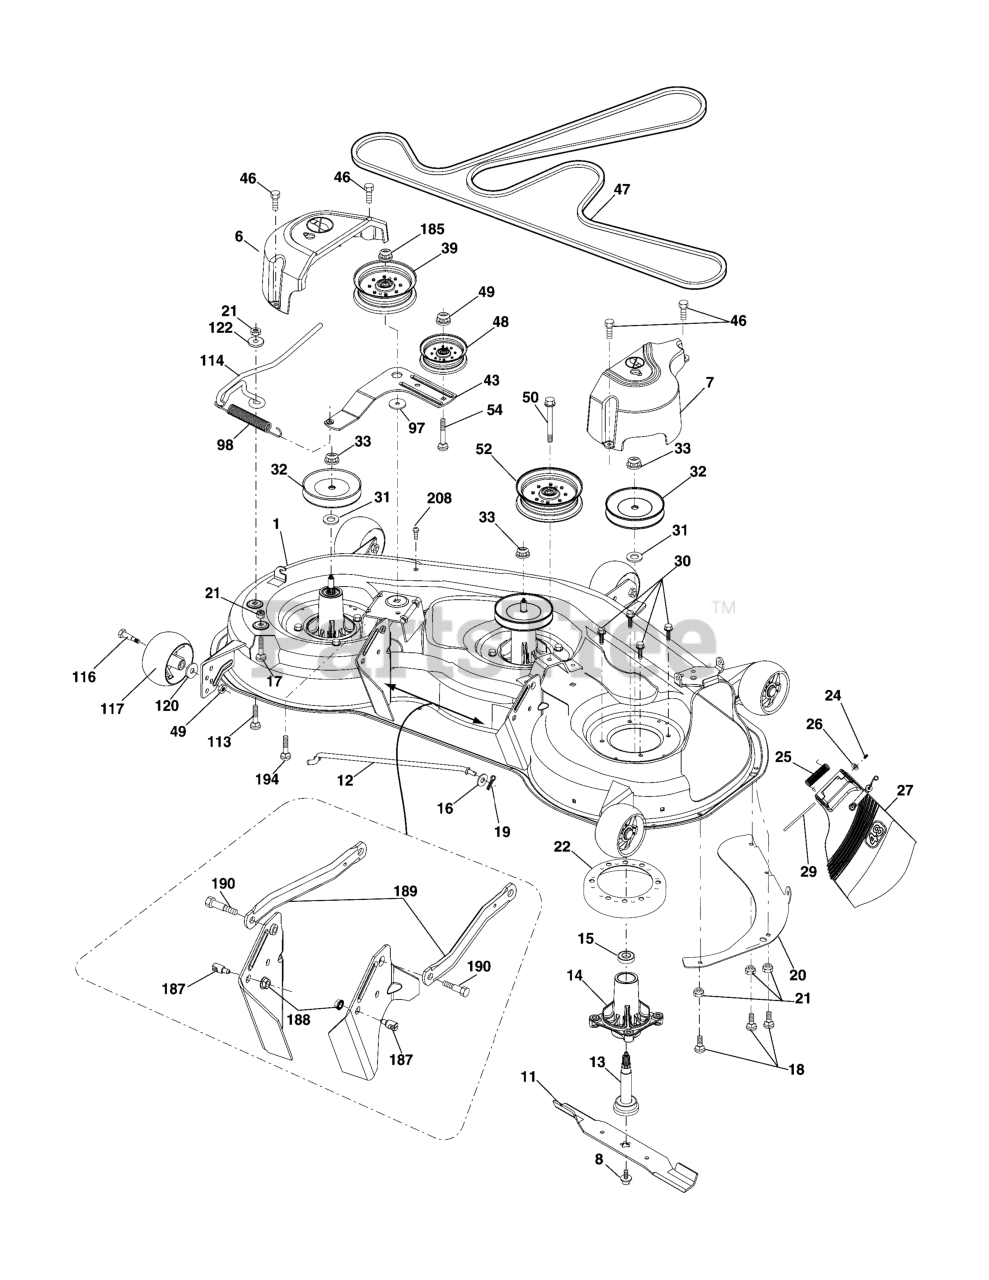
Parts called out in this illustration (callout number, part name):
1	Deck Weldment Mower
6	Cover Mandrel LH
7	Cover Mandrel RH
8	Bolt 7/16 Asm.
11	Blade High Lift
12	Rod Anti-Sway
13	Shaft Asm. w/Lower Bearing
14	Housing, Mandrel
15	Bearing, Ball, Mandrel
16	Washer 13/32 x 13/16 x 12 Ga.
17	Bolt 5/16-18 x 5/8
18	Bolt RdHd 5/16-18 unc x 5/8
19	Pin Cotter 5/16 Bow Tie Lock
20	Baffle Vortex
21	Nut, Crownlock 5/16-18 unc
22	Stripper Mandrel Deck
24	Cap Sleeve
25	Spring, Torsion
26	Nut, Push
27	Deflector Shield
29	Rod, Hinge
30	Screw, Thdroll Washer Head
31	Spacer, Mandrel
32	Pulley, Mandrel
33	Nut, Flg. Top Lock
39	Pulley, Idler
43	Arm, Idler
46	Screw, Thdroll. 1/4-20 x 5/8
47	Belt Drive Deck
48	Pulley Idler Primary
49	Nut, Lock Flg. 3/8-16 unc
50	Screw 3/8-16 x 2-1/4 unc
52	Pulley Idler
54	Bolt Carr. 3/8-16 x 1-1/2 Gr. 5
97	Washer Hardened
98	Spring Drive
113	Bolt Rdhd Sqnk 5/16-18 x 3/4
114	Rod Tension Relief
116	Bolt, Shoulder
117	Gauge Wheel
120	Washer 13/32 x 1-1/4 x 12 Ga.
122	Bushing Tension Relief
185	Nut Lock Flange 7/16-14 Gr. 5
187	Stud Fastr. w/"D" Anti-Rotation
188	Nut Lock Hex Flange
189	Arm Susp. Mower Rear
190	Bolt Shoulder
194	Bolt Carr Sqnk 3/8-16 x 2-1/4
208	Screw 3/8-16 x 1/2
